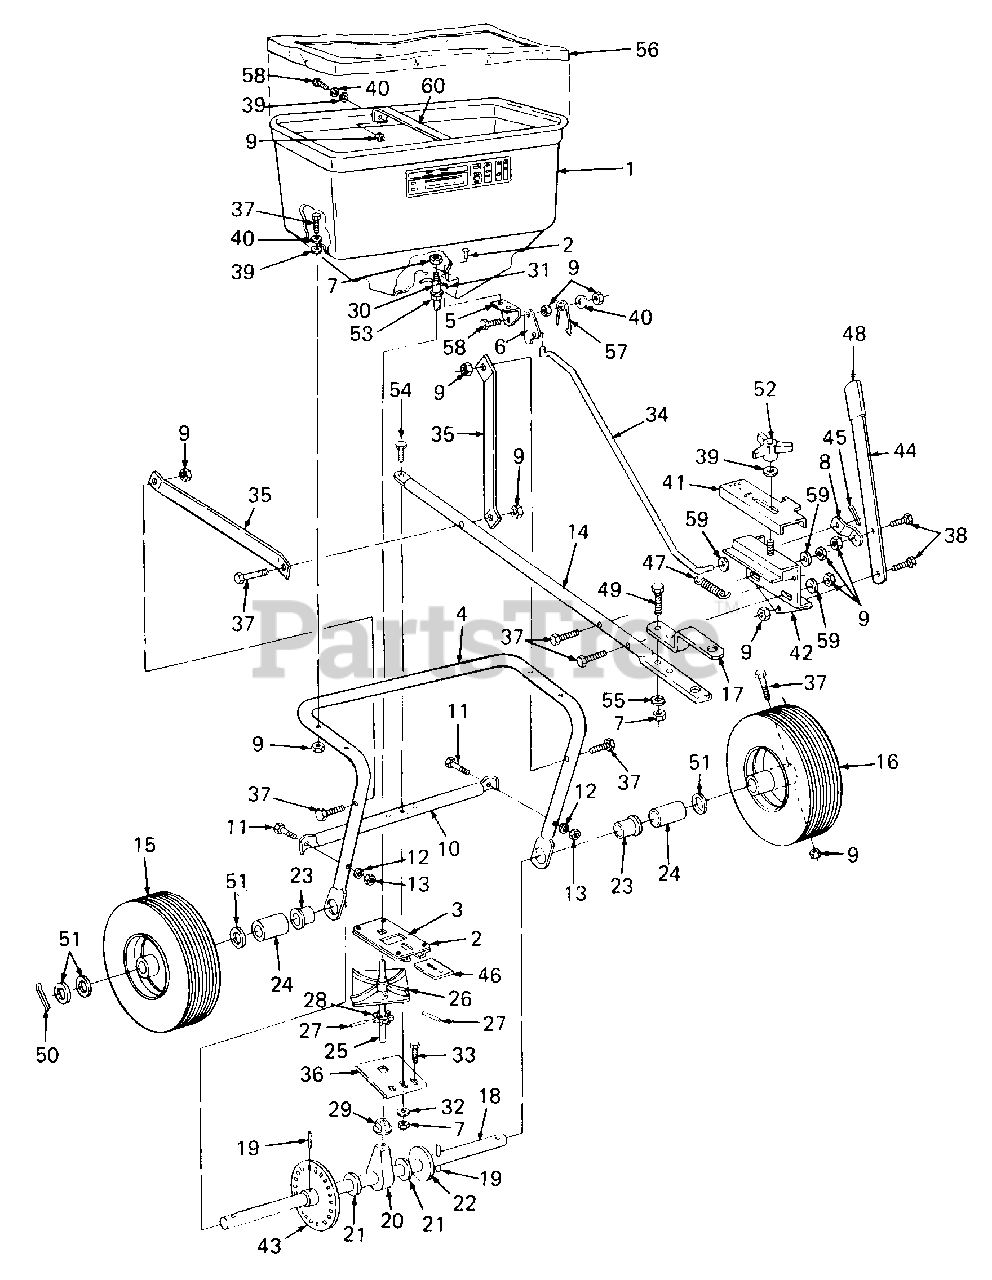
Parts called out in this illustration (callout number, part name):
3	Closure Assy, Guide
4	Support Tube, Hopper/Axle
5	Angle Bracket, Slide Gate
6	Bracket, Slide Gate
7	Nut, Hex Center Lock, 3/8-16
8	Link, Flow Control
9	Nut, Hex Center Lock, 1/4-20
10	Tube-Crossover
11	Screw, Hex Cap, 5/16-18 x 1.75 Lg
12	Washer, Lock, 5/16
13	Nut, Hex Center Lock, 5/16-18
14	Tube, Hitch
15	Wheel Assy, RH, 16 x 4
16	Wheel Assy, LH w/Hole, 16 x 4
17	Bracket, Hitch
18	Shaft, Axle
19	Pin, Roll, 3/6 Dia x 1.25 Lg
20	Bushing, Axle/Shaft
21	Washer, Flat, .781 x 1.59 x .06 Thk
22	Washer, Flat, .81 x 2.0 x .150 Thk
23	Bearing, Flange
25	Shaft, Sprocket
26	Plate, Spreader
27	Pin, Spirol Spring, 1/8 Dia x .62 Lg
28	Sprocket, 6T
29	Bushing, Nylon, .375 ID
30	Sleeve, Agitator
31	Wire, Agitator
32	Washer, Flat, 3/8 ID
33	Screw, Hex Cap, 3/8-16 x 1.75 Lg GR5
34	Rod, Flow Control
35	Brace, Hitch
36	Support, Shaft
37	Screw, Hex Cap, 1/4-20 x 1.75 Lg
38	Screw, Hex Cap 1/4-20 x .62 Lg
39	Washer, Nylon
40	Washer, Flat, .281 x .73 x .063 Thk
41	Gage, Flow Control
42	Mount Assy, Flow Control
43	Gear Assy
44	Arm, Flow Control
45	Pin, Cotter, 3/32 Dia x .75 Lg
46	Plate, Closure
47	Spring, Extension
48	Grip, Flow Control Arm
49	Screw, Hex Cap, 3/8-16 x 1.25 Lg
50	Pin, Cotter, 1/8 Dia x 1.50 Lg
51	Washer, Flat, .781 x 1.59 x .065 Thk
52	Knob, Plastic, 1/4-20
53	Bushing, Delrin, .375 ID
54	Screw, Hex Cap, 3/8-16 x 2.00 Lg GR5
55	Washer, Lock, 3/8
56	Cover, Vinyl Hopper
57	Spring, Torsion
58	Screw, Hex Cap, 1/4-20 x .75 Lg GR5
59	Washer, Flat
60	Strap, Hopper
